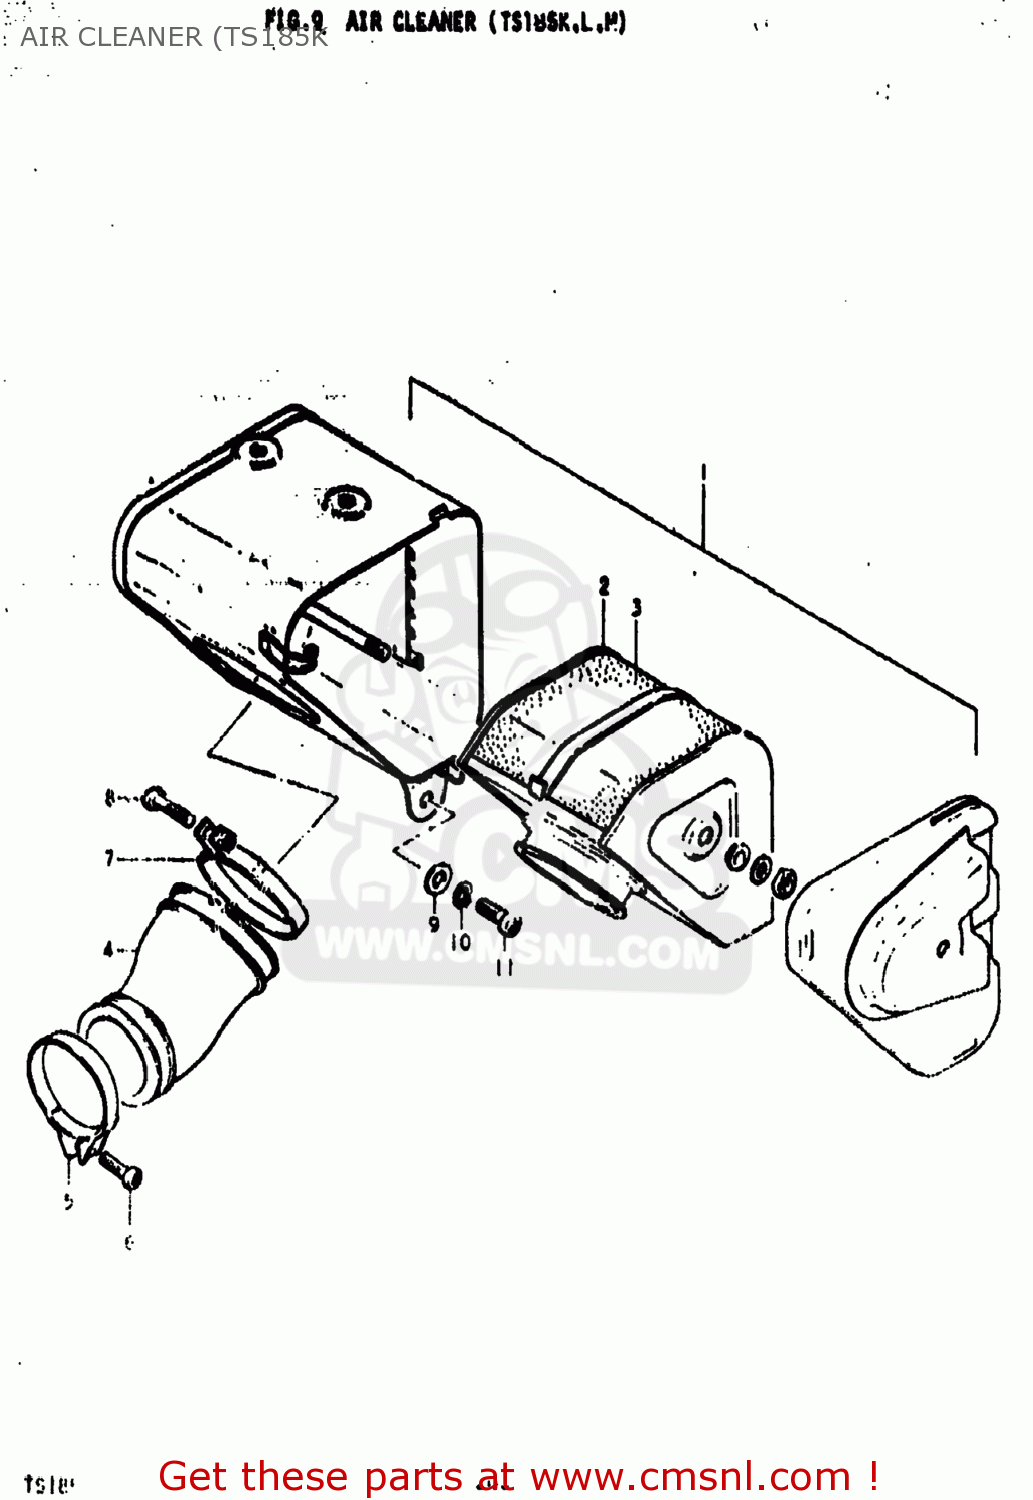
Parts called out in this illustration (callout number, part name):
1	CLEANER ASSEMBLY,AIR
2	FILTER,AIR CLEANER
3	FILTER
4	HOSE,CARBURETOR AIR INLET
5	CLAMP
6	SCREW
7	CLAMP
8	SCREW
9	WASHER
10	LOCK WASHER
11	SCREW 6X12
